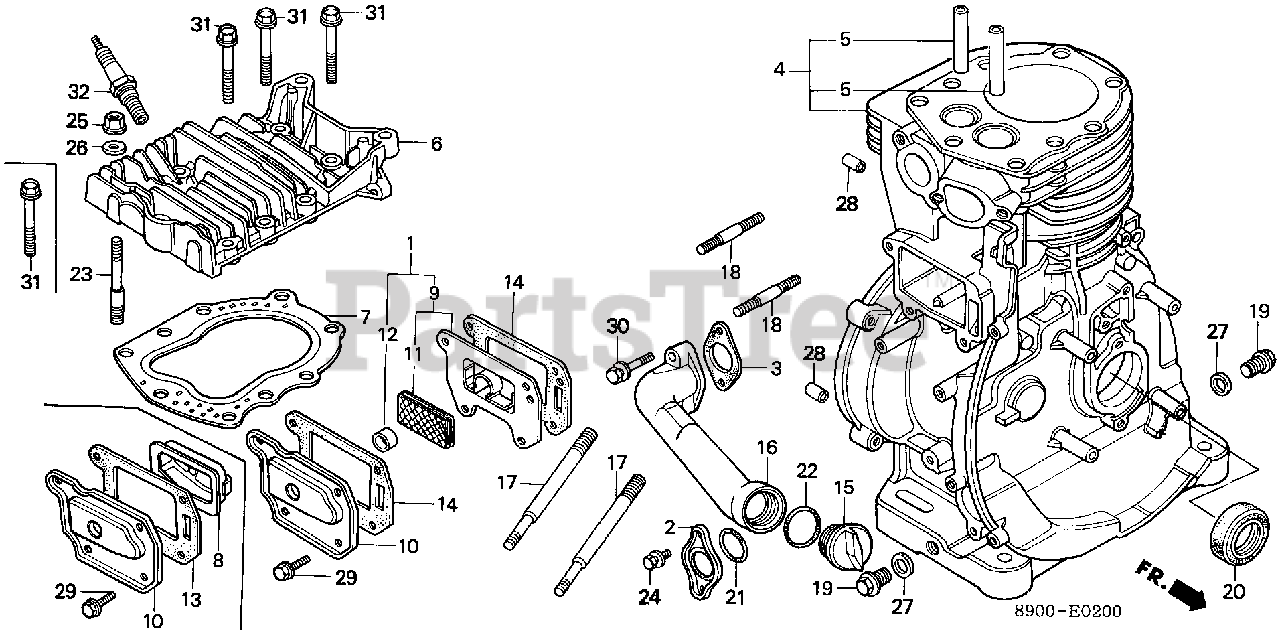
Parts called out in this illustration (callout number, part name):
1	CASE KIT, BREATHER (NOT AVAILABLE)
2	COVER, OIL PAN HOLE
3	GASKET, OIL PAN
4	CYLINDER (CRANKSHAFT P.T.O.) (NOT AVAILABLE)
4	CYLINDER (CRANKSHAFT P.T.O.)
5	GUIDE, VALVE
6	CYLINDER HEAD (NOT AVAILABLE)
7	GASKET, CYLINDER HEAD
8	CASE, BREATHER
9	CASE, BREATHER
10	COVER, TAPPET ROOM
11	FILTER, BREATHER
12	SEAL, BREATHER
13	GASKET, TAPPET COVER
14	GASKET, TAPPET COVER
15	CAP, OIL (YELLOW)
16	PIPE, OIL
17	BOLT, STUD (8X104)
18	BOLT, STUD (8X35)
19	BOLT, DRAIN PLUG (12X15)
20	OIL SEAL (30X46X8)
21	O-RING (27X2.0)
22	O-RING (26X2.7)
23	BOLT, STUD (10X70)
23	BOLT, STUD (10X40)
24	BOLT-WASHER (6X12)
25	NUT, FLANGE (10MM)
26	WASHER, PLAIN (10MM)
27	WASHER, DRAIN PLUG (12MM)
28	PIN, DOWEL (8X14)
29	BOLT, FLANGE (6X12)
30	BOLT, FLANGE (6X25)
31	BOLT, FLANGE (10X55)
32	SPARK PLUG (B-4H) (NGK)
32	SPARK PLUG (BR-4HS) (NGK)
32	SPARK PLUG (BP-4HS-10) (NGK)
32	SPARK PLUG (BPR-4HS-10) (NGK)
32	SPARK PLUG (BPR4HS-10)
32	SPARK PLUG (BP4HS-10)
32	SPARK PLUG (W14F-U) (DENSO)
32	SPARK PLUG (W14FR-U)
32	SPARK PLUG (W14FP-UL10) (DENSO)
32	SPARK PLUG (W14FPR-UL10) (DENSO)
32	SPARK PLUG (W20FS-U) (DENSO)
32	SPARK PLUG (W20FP-U10) (DENSO)
